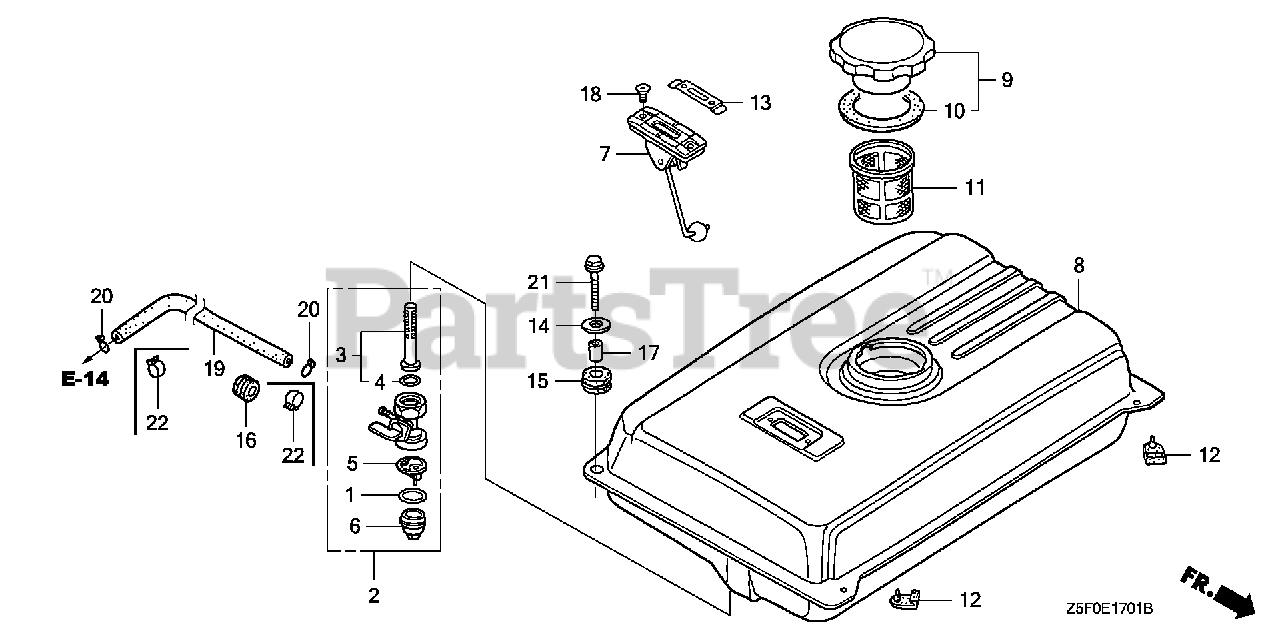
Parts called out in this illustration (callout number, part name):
1	GASKET, FUEL STRAINER CUP
2	PETCOCK ASSY.
3	SCREEN SET, FUEL STRAINER
4	O-RING (9.0X1.3)
5	FILTER, CUP
6	CUP, FUEL STRAINER
16	RUBBER, FUEL (9X15X20)
19	TUBE, FUEL (4.5X190) (FKM)
22	CLIP, TUBE (D8)
